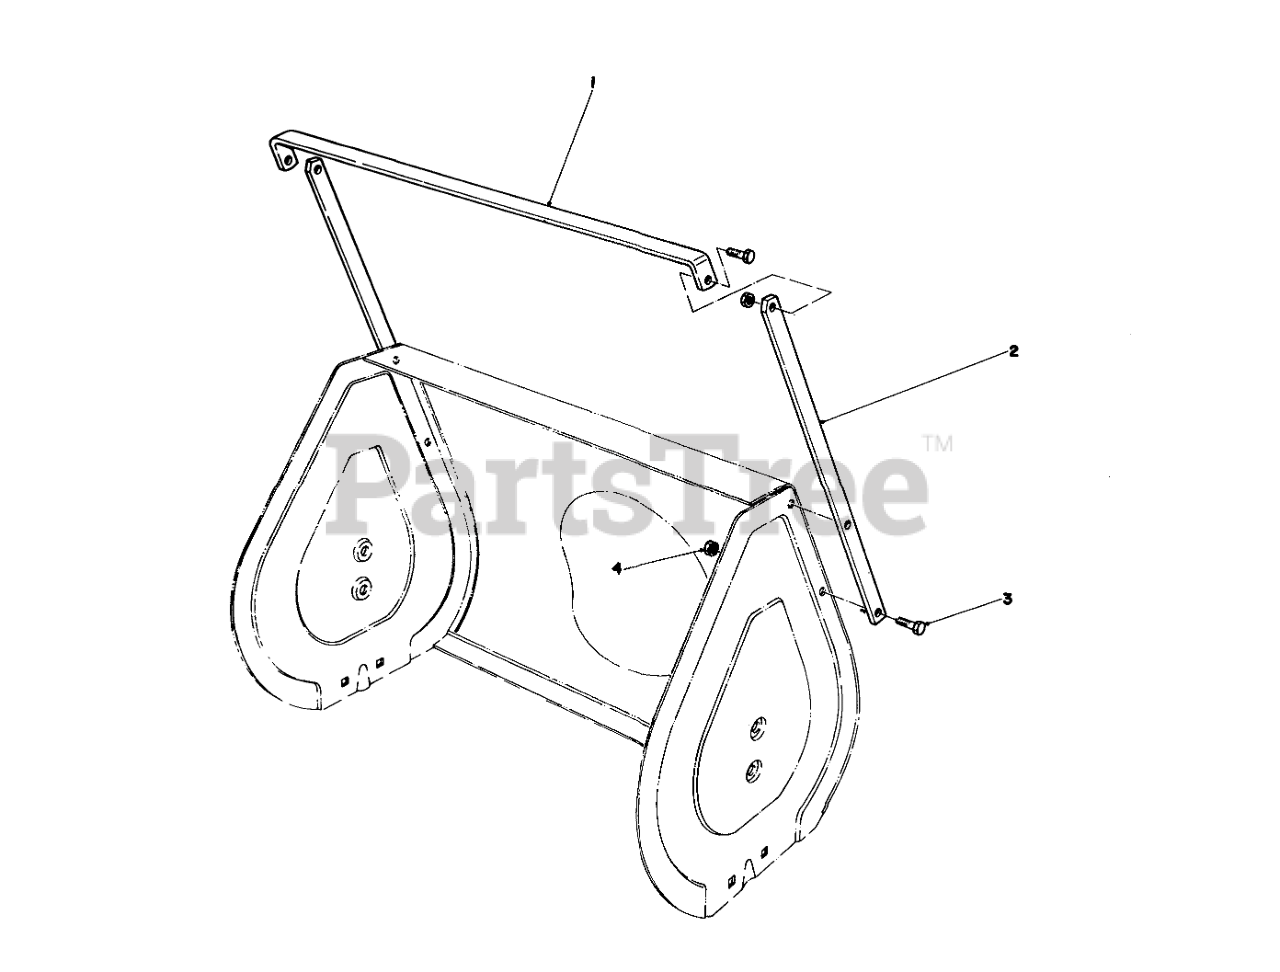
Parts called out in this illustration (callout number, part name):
1	Drift Breaker-Top
2	Drift Breaker-Side
3	SCREW-HH
4	NUT-LOCK, NI
